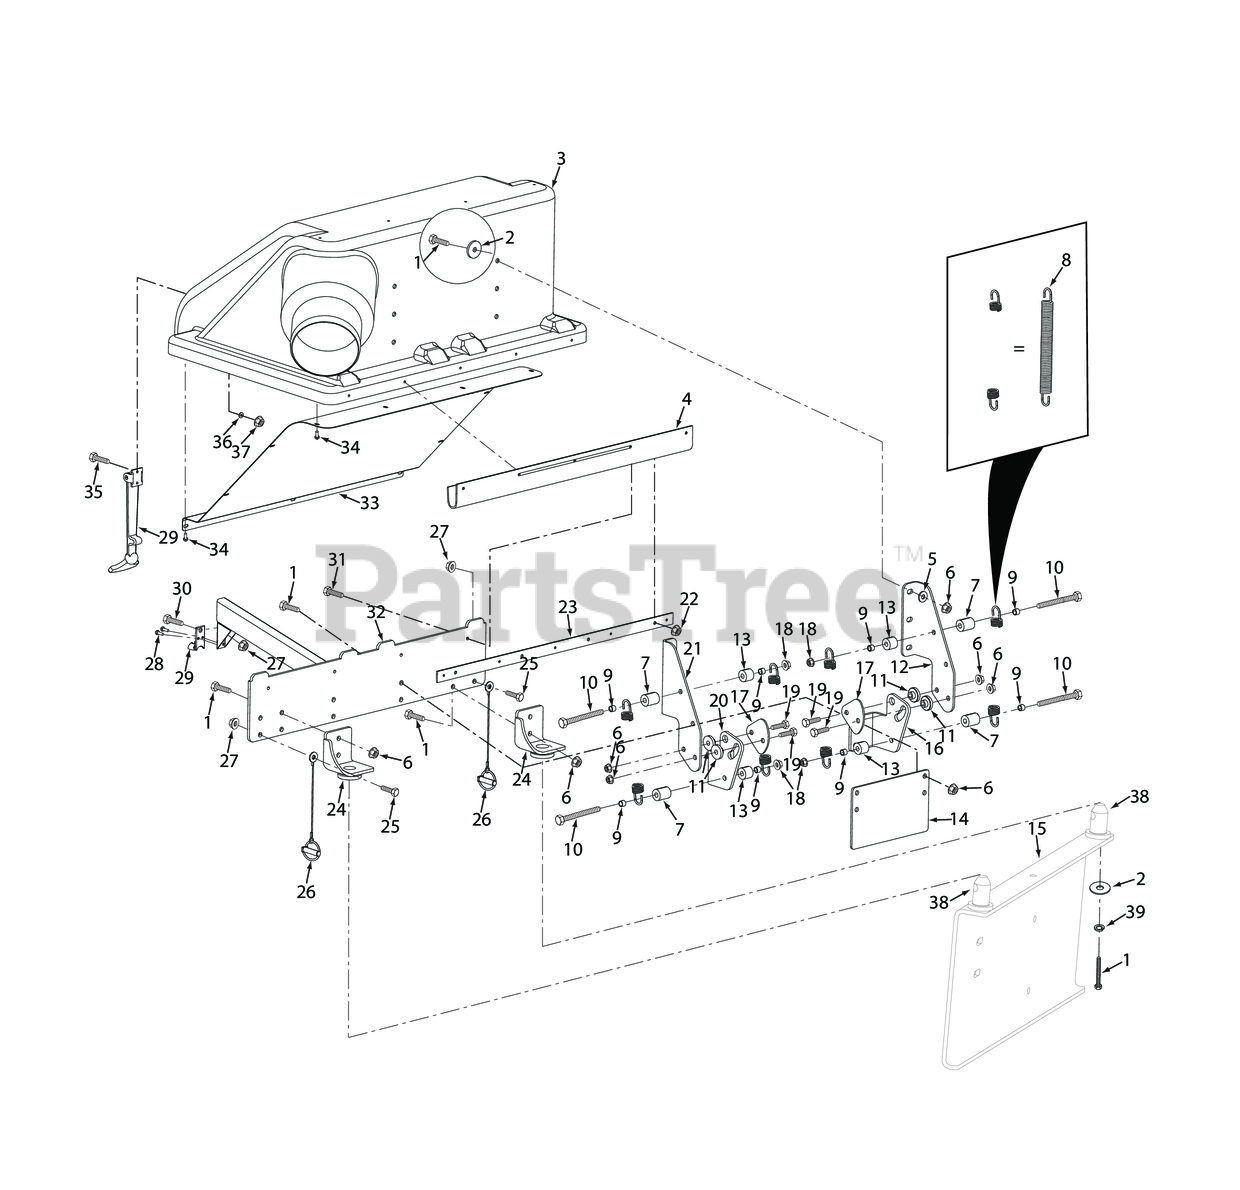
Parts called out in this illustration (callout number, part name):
1	Bolt, Hex Head 3/8-16 x 1-1/4", Kawasaki FX / FS
2	Flatwasher, 3/8-.406 x 1-1-1/2 x 7 Gauge
3	Hood Assembly
4	Diode (part of wire harness)
5	Flatwasher, 3/8" Special (.391 x .938 x .105)
6	HEX NUT, ELASTIC STOP LOCK, 3/8-16
7	Spacer
8	Spring, Hood Hinge
9	Spacer, Deck Assist
10	Bolt, Hex Head 3/8-16 x 4.00
11	Bushing, Hopper Pivot
12	Hinge, Upper LH
13	SPACER, J-PULL ROD
14	Plate, Support
15	Bag Support Plate
16	Hinge, Lower LH
17	Guard, GC Hinge
18	Bolt, Hex Head 3/8-16 x 1" Ser. Flg.
19	Bolt, Hex Head, 3/8-16 x 1-1/2"
20	Hinge, Lower RH
21	Hinge, Upper RH
22	Bolt, Hex Hd. 1/2-13 x 9-1/2"
23	Retainer, Seal
24	Receiver, Weldment
25	Bolt, Heax Head 5/16-18 x 1" (48V / 52V)
26	Quick Pin Assembly
27	HEX NUT, ELASTIC STOP LOCK, 5/16-18
28	Rivot, 3/16 x .402 POP
29	Latch, Hopper
30	BOLT, SERRATED FLANGE HEX HEAD 5/16-18 X 3/4"
31	BOLT, HEX HEAD, 1/4-20 X 3/4 GR.5
32	Frame Weldment, Bag Support
33	Screen, GC Hood
34	Pop Rivet, 3/16 x .652"
35	Screw, #10-32 x 3/4"
36	Flatwasher, 3/16 (.196 x .469 x .048)
37	HEX NUT, ELASTIC STOP LOCK # 10-32
38	Pin, GC Locator
39	Lockwasher, 3/8" Spring, Kawasaki FX / FS
